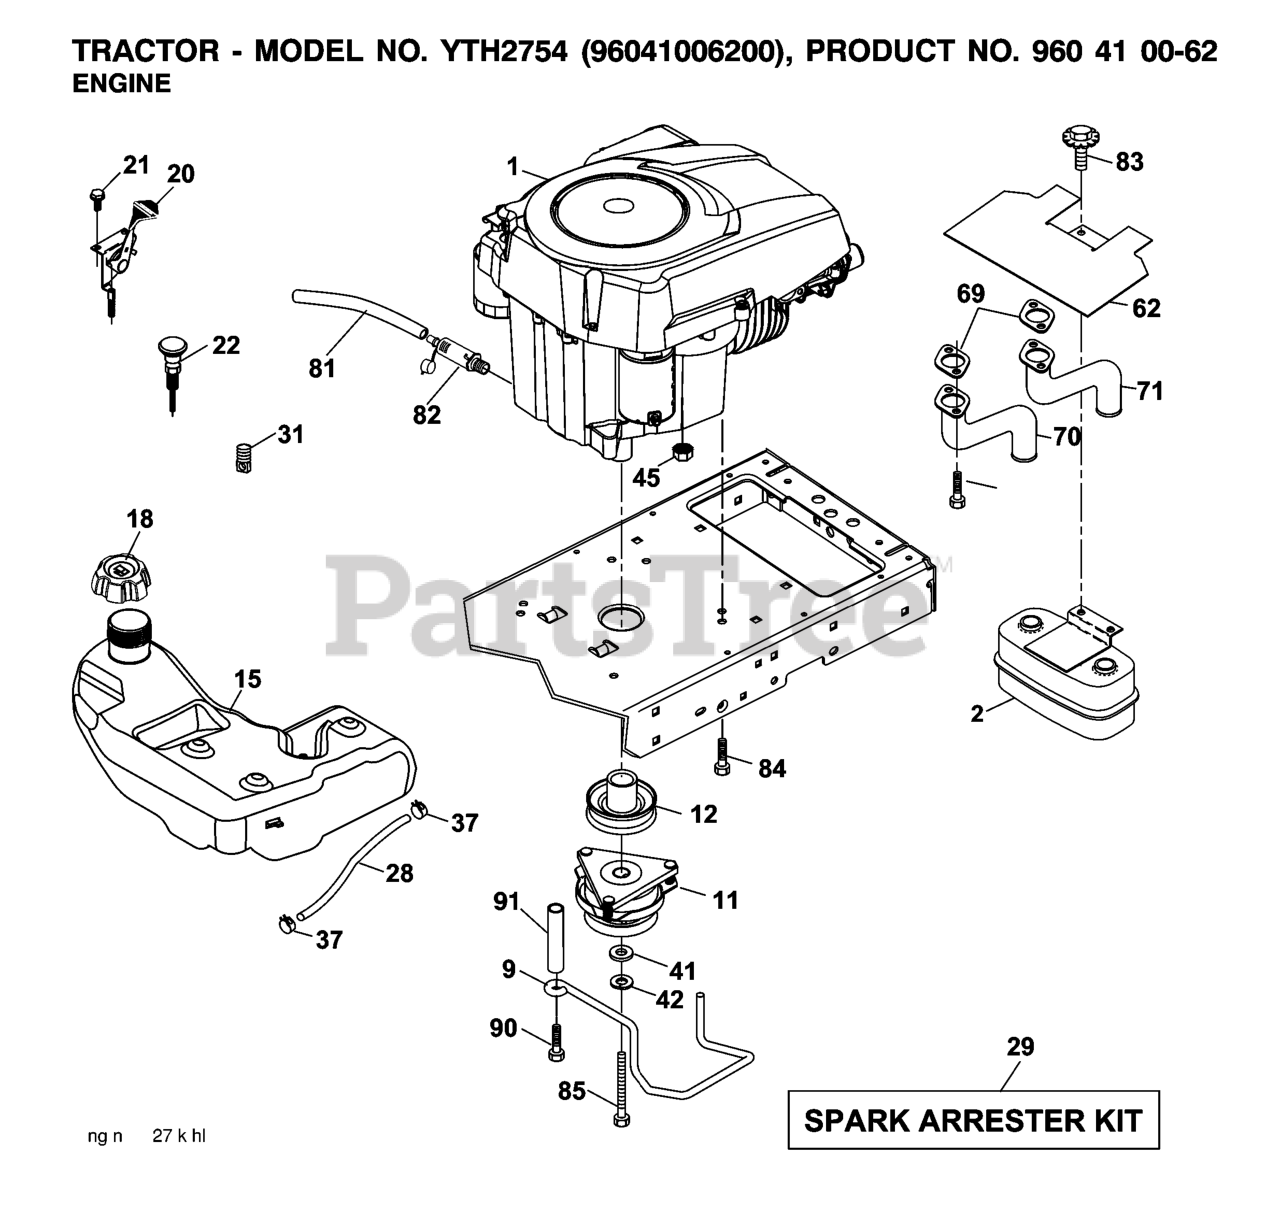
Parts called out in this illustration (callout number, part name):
2	MUFFLER.TWIN.CYL.LOW.TONE
9	KEEPER.BELT.ENGINE.4.2
11	CLUTCH MZ ZTR GT.48/54"1.125"
12	PULLEY ENGINE
15	TANK.FUEL.4GAL
18	CAP.FUEL.TANK.3"GREY
20	THROTTLE CONTROL
21	SCREW
22	CONTROL.CHOKE.ERGO.PUSH-IN.BLA
28	REPL BY 532 00 85-43
29	KIT.SPARK ARRESTOR 794945 B&S
37	HOSE CLAMP
42	LOCKWASHER
45	NUT
62	RP SHIELD HEAT MUFFLER
70	RP.PIPE-EXHAUST LH
71	RP.PIPE-EXHAUST RH
79	SCREW.SOCKET HD.5/16-1
81	TUBE, DRAIN OIL ASM.
82	PLUG DRAIN OIL EASY
83	BOLT.5/16-18UNCX1.W/SEMS.BLK
84	SCREW 3/8-16X1
85	BOLT HEX 7/16-20 X 3.75 GR. 5
90	SCREW 3/8-16X1
91	BUSHING.1.375OD
